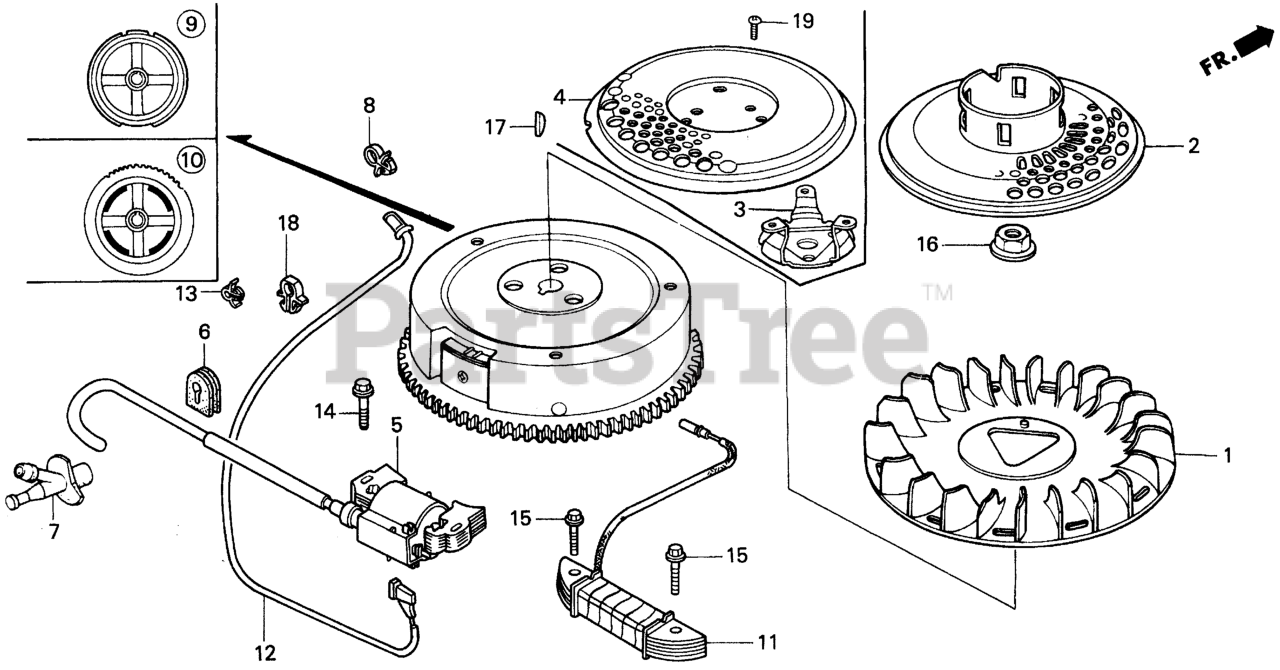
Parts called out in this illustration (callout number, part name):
1	FAN, COOLING
2	PULLEY, STARTER (SCREEN GRID)
5	COIL ASSY., IGNITION
6	GROMMET, IGNITION
7	CAP ASSY., NOISE SUPPRESSOR
9	FLYWHEEL
12	WIRE, STOP SWITCH
13	HOLDER, STOP SWITCH WIRE Use up to Engine SN 2056819.
14	BOLT, FLANGE (6X28) (CT200) Use up to Engine SN 1530314.
16	NUT, SPECIAL (16MM) (1)
16	NUT, SPECIAL (16MM)
17	KEY, SPECIAL WOODRUFF (25X18)
18	CLIP, HOOD OPEN WIRE
